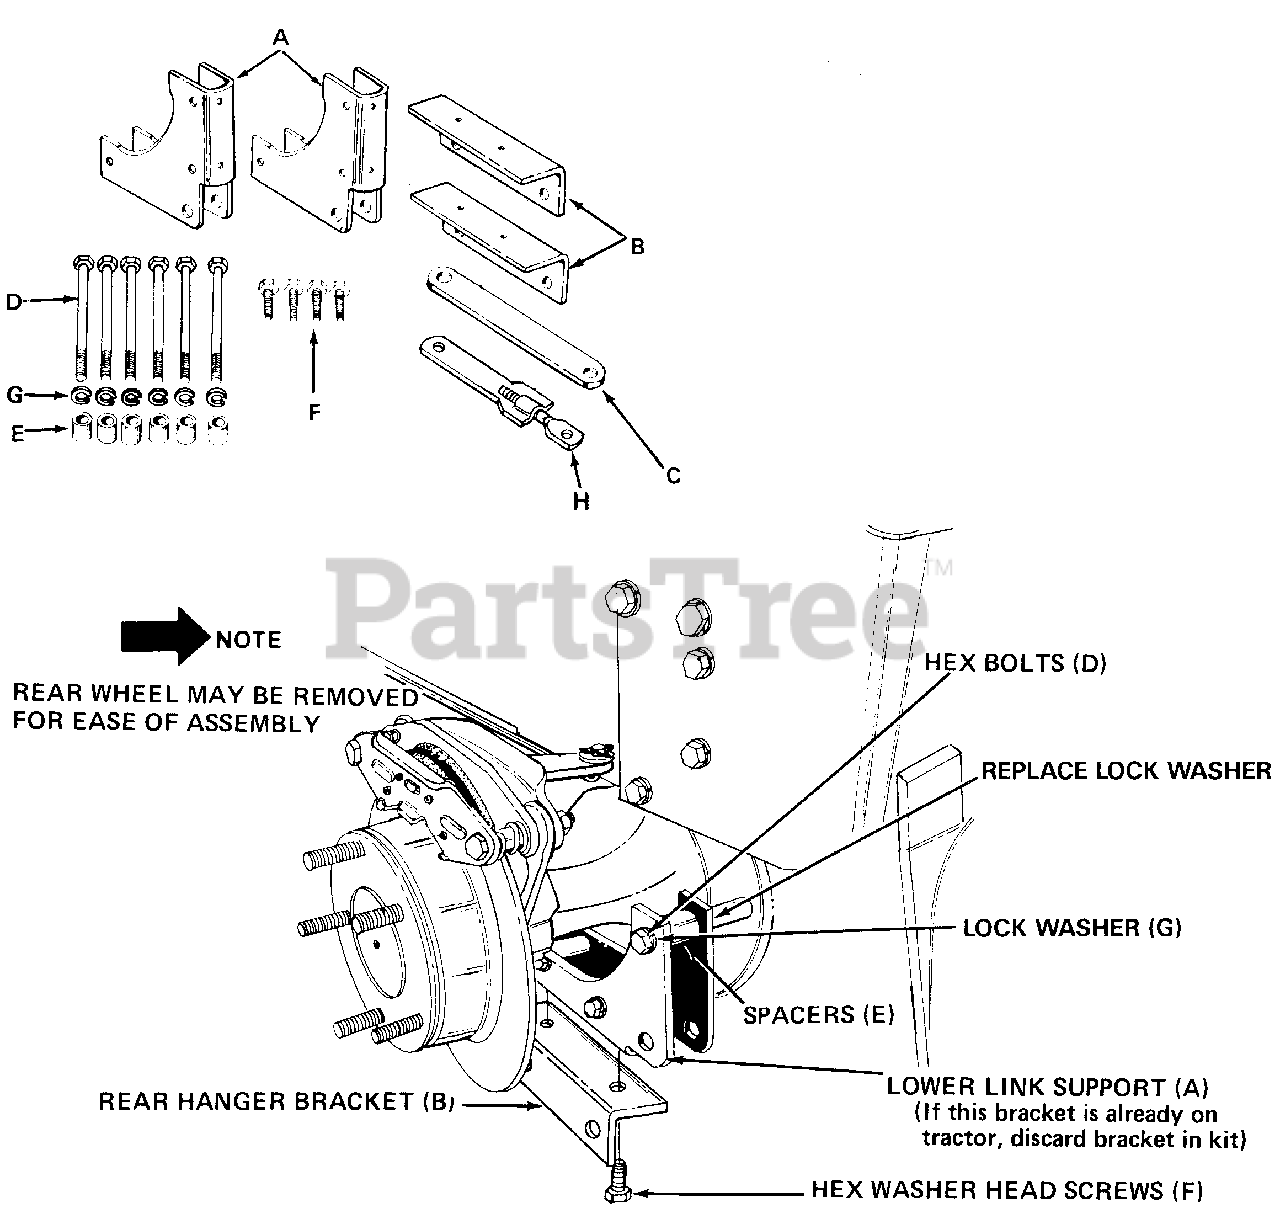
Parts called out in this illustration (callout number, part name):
A	Lower Link Support Plates
B	Rear Hangar Brkt.
C	Lift Bracket 8-3/4" Lg.
D	Hex Bolts
E	Support Spacers
F	Hex Wash. Hd. Self Tap Scr
G	Lock Washers
H	Adjustable Link
